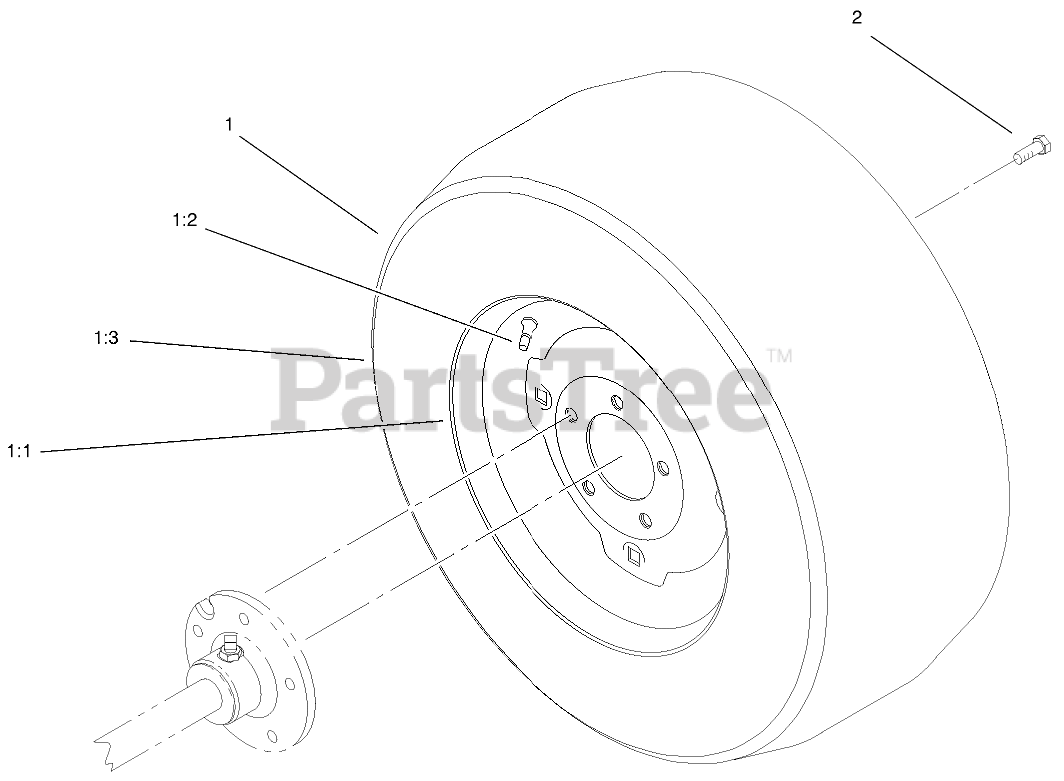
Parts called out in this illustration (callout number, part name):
1	Rear Wheel & Tire ASM (Only On: 73470, 73540)
1	Rear Wheel & Tire ASM (Only On: 73541)
1:1	Tire (Only On: 73470, 73540)
1:1	Tire (Only On: 73541)
1:2	VALVE
1:3	RIM ASM
2	BOLT-LUG
